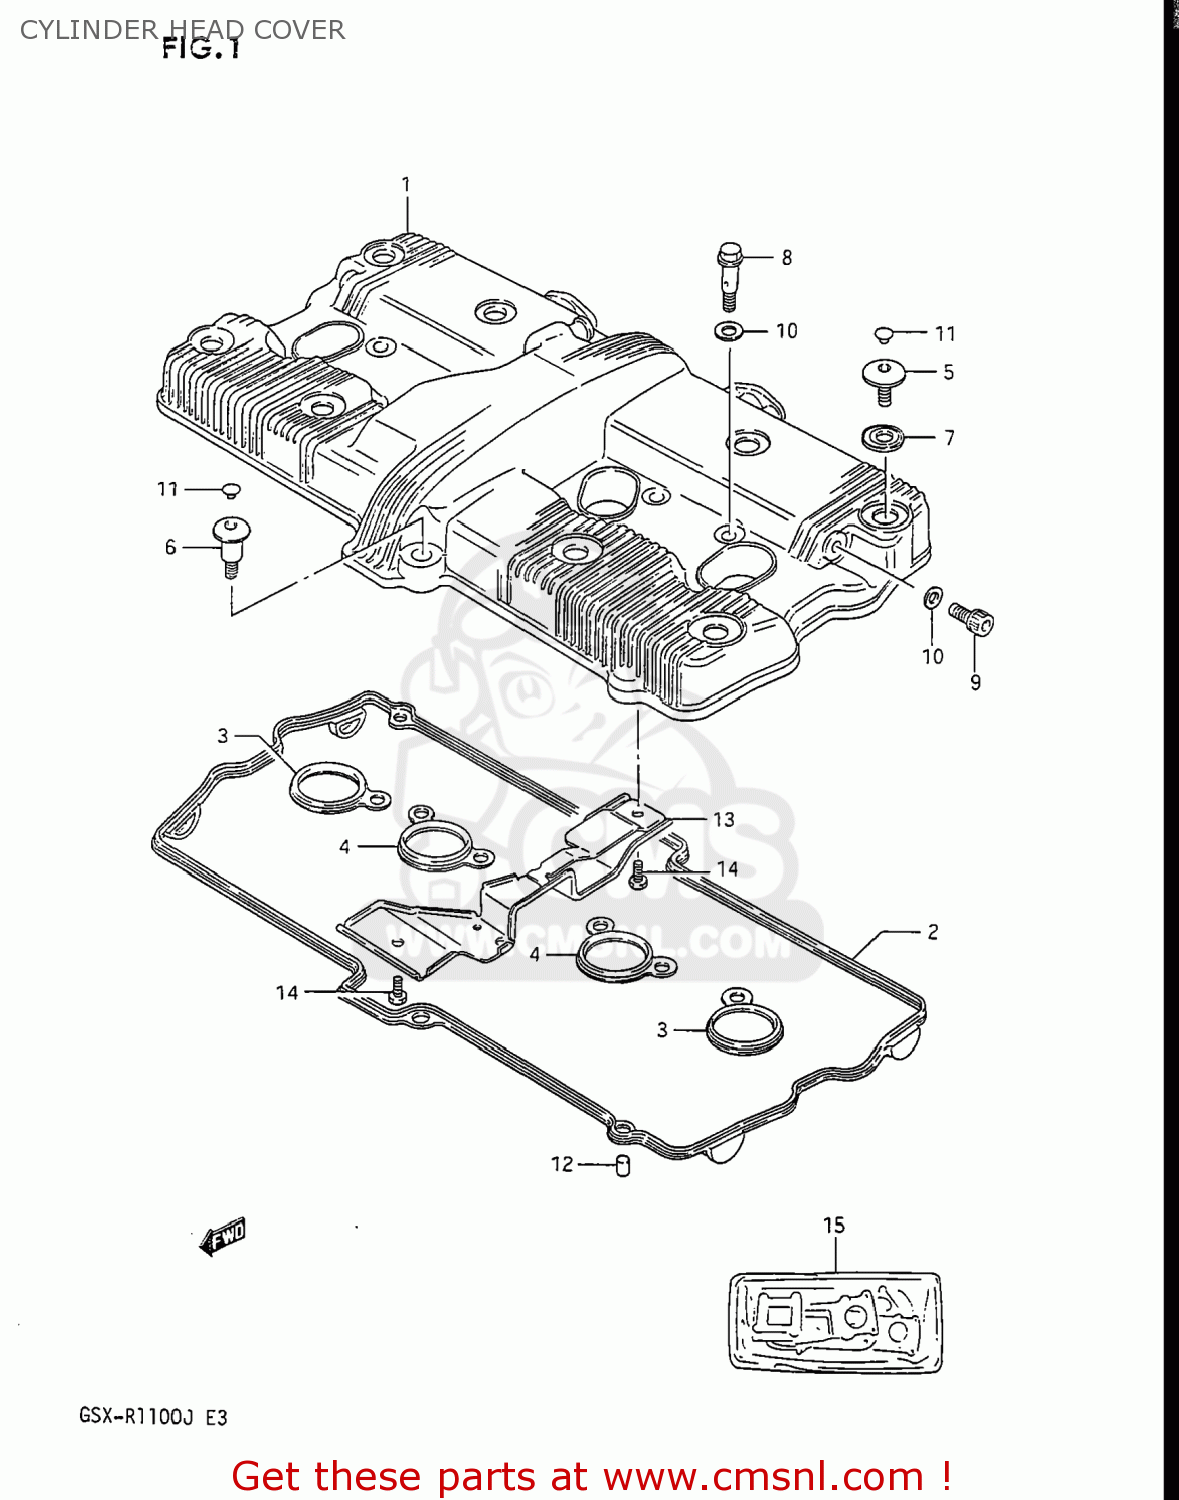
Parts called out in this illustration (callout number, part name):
1	COVER,CYLINDER HEAD
2	GASKET,CYLINDER HEAD COVER (NAS)
3	GASKET (NAS)
4	GASKET,HEAD COVER NO.3 (NAS)
5	BOLT(7X17.5)
6	BOLT(7X31)
7	WASHER
8	BOLT,UNION 8X35
9	PLUG, HEAD COVER
10	GASKET 8.2X14X1 (NAS)
11	CAP(OD:10)
12	PIN
13	COVER,BREATHER
14	BOLT 5X12
15	GASKET SET
